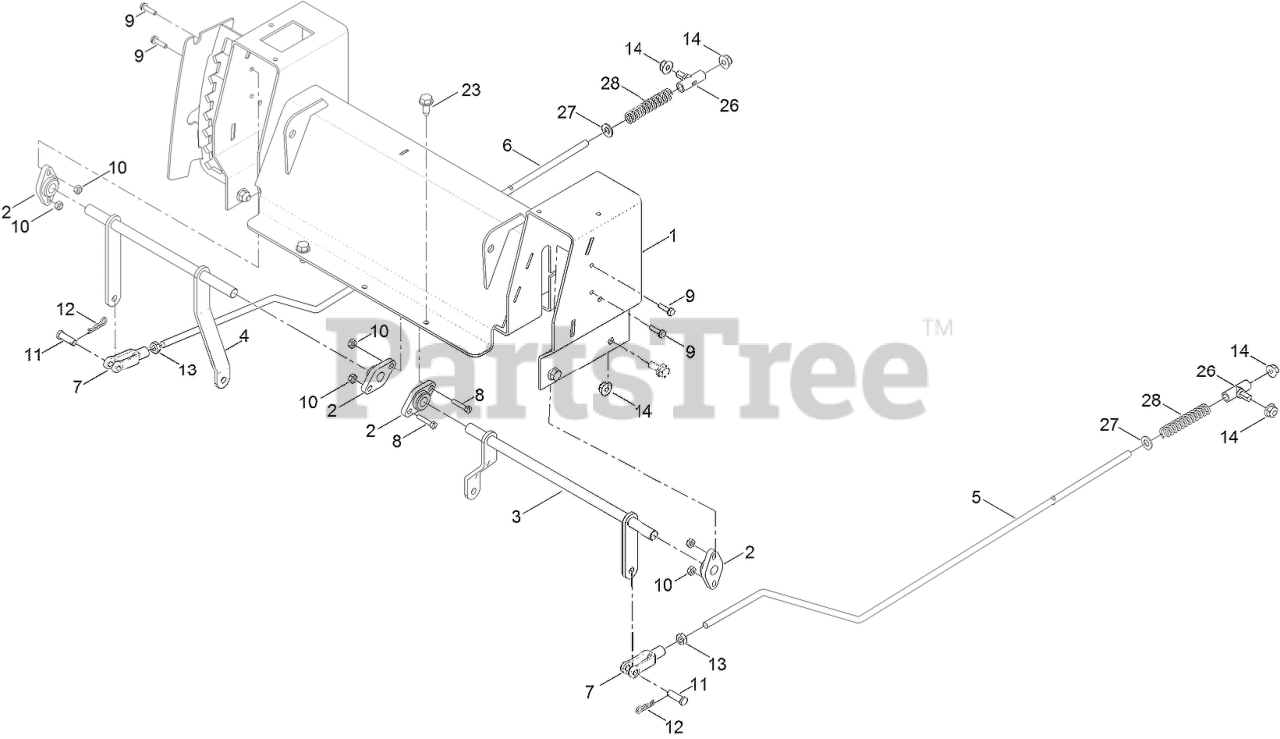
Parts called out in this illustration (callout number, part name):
1	CONTROL BOX ASM
2	BEARING-FLANGE
3	BELLCRANK-LH
4	BELLCRANK-RH, NARROW
4	BELLCRANK-RH
5	ROD-HYDRO, LH
6	ROD-HYDRO, RH
7	YOKE-ADJUSTABLE
9	SCREW-HWH
10	NUT-LOCK, NI
11	PIN-CLEVIS
12	PIN-COTTER
13	NUT-JAM
13	SCREW-HHF
14	NUT-HF, NI
23	SCREW-HWHTF
26	MOUNT-ROD, HYDRO
27	WASHER-PLAIN
28	SPRING-RETURN, NEUTRAL
